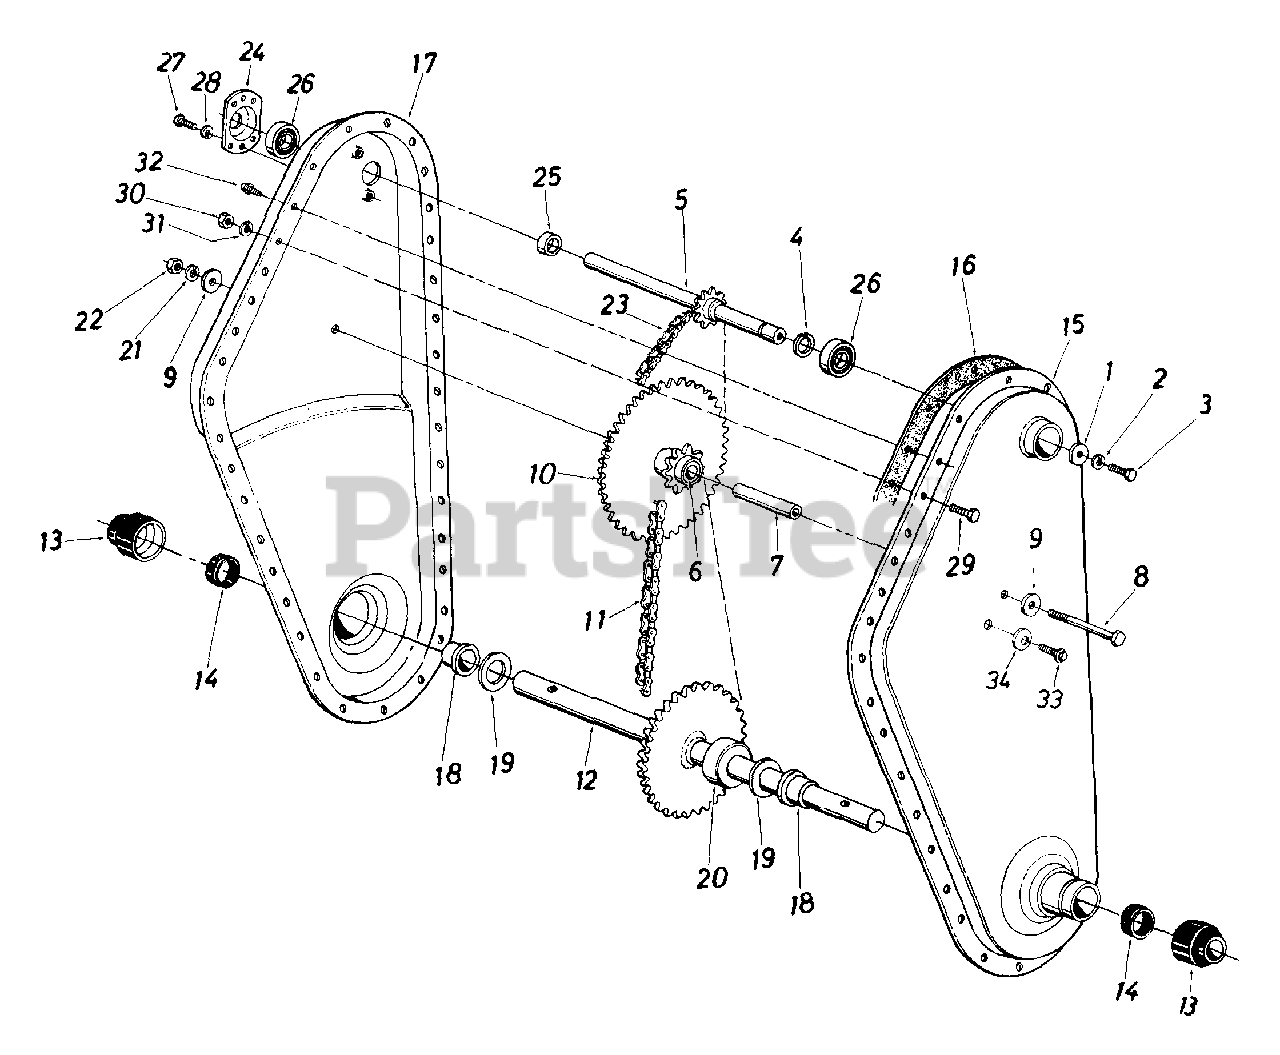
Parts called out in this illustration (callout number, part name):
1	Fl-Wash. 1/4" I.D. x .93" O.D.
2	L-Wash. 1/4" l.D.
3	Hex Bolt 1/4-28 x .62" Lg. w/Patch
4	External Snap Ring - 5/8" Dia.
5	Input Shaft Ass'y.
6	Bearing 5/8" l.D. x 3/4" O.D. x 1.860" Lg.
7	Sprocket Hub Tubing 3/8" I.D. x 5/8" O.D. x 1.90
8	Hex Bolt 3/8-24 x 2.75" Lg.
9	Fl-Wash. 3/8" l.D. x 1.25"
10	Sprocket Ass'y.
11	#50 Chain 5/8" Pitch x 46 Links Endless
12	Tine Shaft Ass'y.
13	Dust Cup
14	Seal Ring Single Lip
19	Fl-Thrust Wash. 1.0" I.D. x .03 Thk.
20	Step Spacer
21	L-Wash. 3/8" I.D.
22	Hex Nut 3/8-24 Thd.
23	#35 Chain 3/8" Pitch x 52 Links Endless
24	Bearing Housing 1.38" I.D.
25	Spacer
26	Ball Bearing .625" I.D. x 1.38" O.D. x .437
27	Hex Wash. SF-Tap Scr. 1/4-20 x .50" Lg.
28	L-Wash. 1/4" I.D.
29	Hex Bolt 5/16-18 x .75" Lg.
30	Hex Nut 5 16-18 Thd.
31	L-Wash. 5 16" I.D.
32	Hex Wash. SF-Tap Scr. 1/4-20 x .50" Lg.
33	Hex Wash. Hd. Tap Scr. 1/4-20 x .38" Lg.
34	Bell-Wash..265" I.D. x .75"
